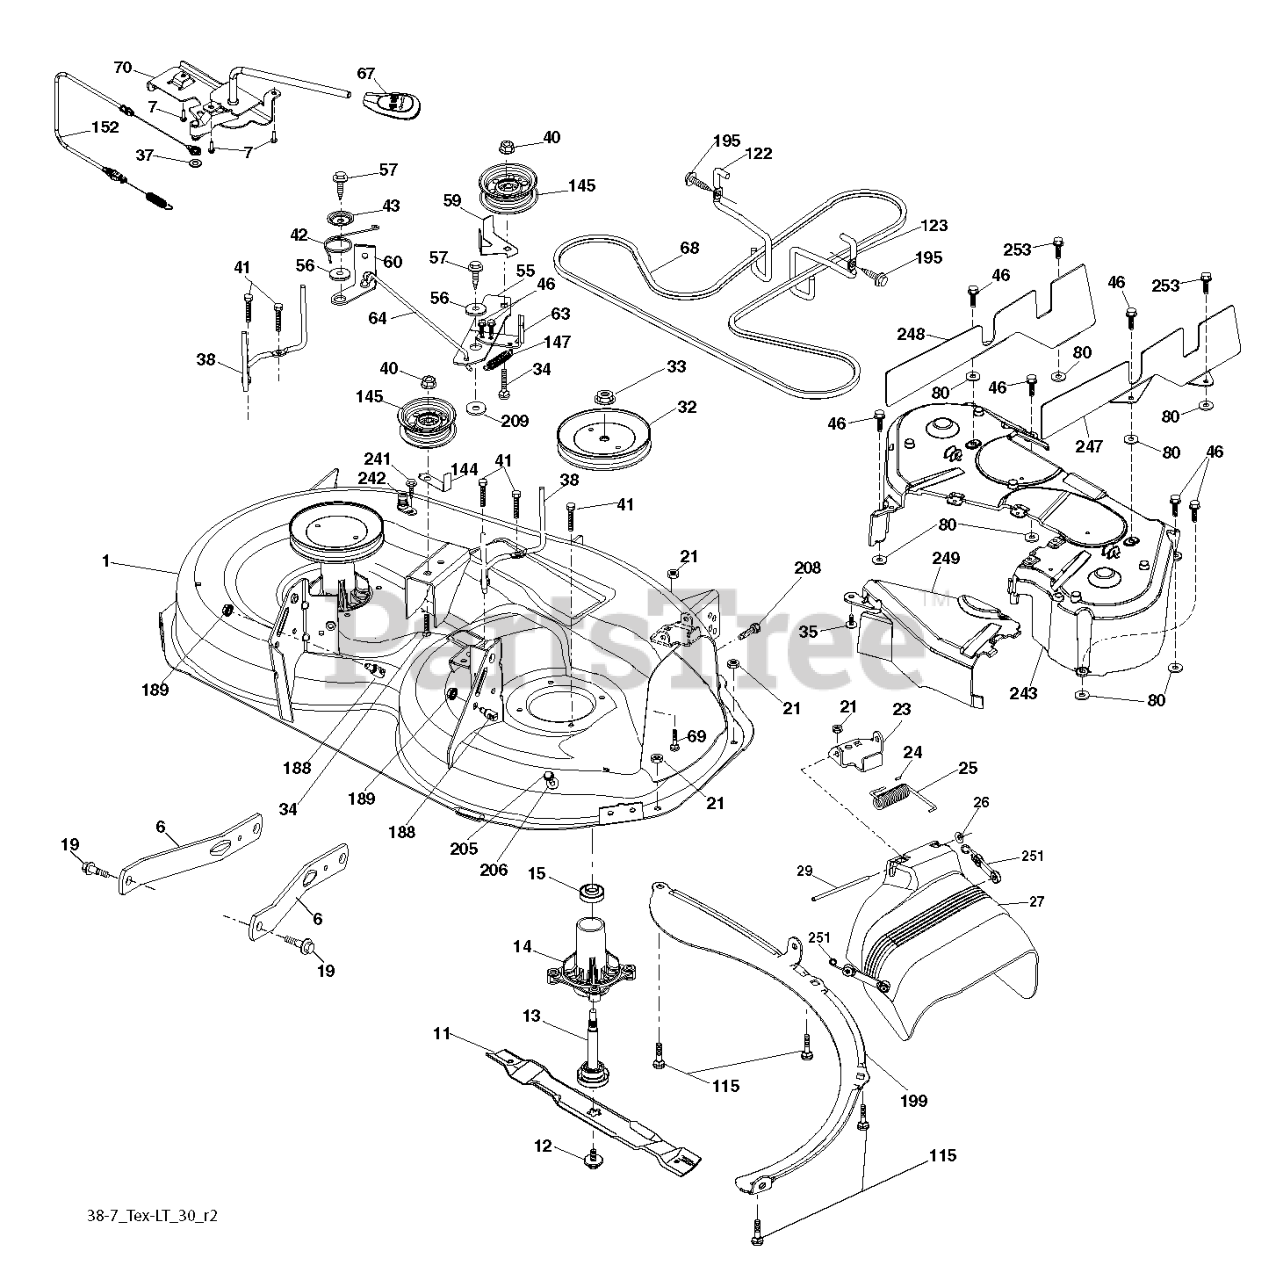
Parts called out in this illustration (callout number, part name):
1	DECK.WELD.38.NGW.TX.W/HOL.GREY
6	ARM.SUSPENSION.MOWER.R
7	SCREW.#10 X 0.750.BOS
8	BOLT.WASHER.ASM.7/16-2
11	BLADE 38" PREMIUM
13	SHAFT.ASM.MDRL.N/GREASE.38
14	RP.HOUSING.MANDREL.4PT.
19	BOLT.SHOULDER
21	LOCKNUT
23	BRKT.DEFLECTOR.38"2005+
24	CAP-SLEEVE LT
25	SPRING.TORSION.DEFLECT
26	NUT PUSH M
27	SHIELD ASM.DFLCTR MWR.38-7"BLK
29	ROD.HINGE
31	WASHER.SPACER.MANDREL
32	PULLEY.MANDREL.5.0.PD.38"
33	NUT.FLANGE.LOCK.TOP
34	BOLT.3/8-16X1.50
35	FASTENER.XMAS.TREE
37	WASHER
38	KEEPER BELT LH MANDREL
40	NUT LOCK FLG 3/8-16 UNC
41	BOLT.HEX.WASHR.HED.313-18X1.19
42	SPRING.TORSION.BRAKE
43	SRPING.TORSION.RETAINE
46	SCREW.1/4-20X5/8
55	IDLER.ARM
56	SPACER.RETAINER
57	SCREW 3/8-16X1
59	GUARD, BELT
60	ARM BRAKE MOWER RH 38"
63	RP ARM.BRAKE.MOWER.38"LH.TEX
64	LINK BRAKE
67	HANDLE.CLUTCH.CABLE.LT
69	BOLT
70	CLUTCH.ASM.MANUAL.LT.PRED
80	PALNUT 1/4
115	BOLT.CARR.5/16-18X5/8.SHORT
122	KEEPER BELT ENGINE LH
123	KEEPER BELT RH
144	KEEPER BELT
145	PULLEY.IDLER.48"PRIMARY
147	SPRING RETURN
152	CABLE.CLUTCH.MANUAL.
188	STUD.FASTNER.W/ANTI-ROTATE
189	NUT LOCK HEX FLANGE 5/16-18
195	SCREW, 3/8-16X3/4
199	BAFFLE.VORTEX.FRONT.38"
206	Washer, 9/32 X 7/8 X 16 Gauge
209	WASHER 12/32X2X10GA
241	SCREW.TT.#10-32X.5.3/8.FLANGE
242	PORT.WASHOUT
243	COVER DECK 38-7
247	SHIELD DECK RIGHT
248	SHIELD DECK LEFT
249	COVER CABLE CLUTCH
251	ELASTIC STRAP KIT
253	SCREW
